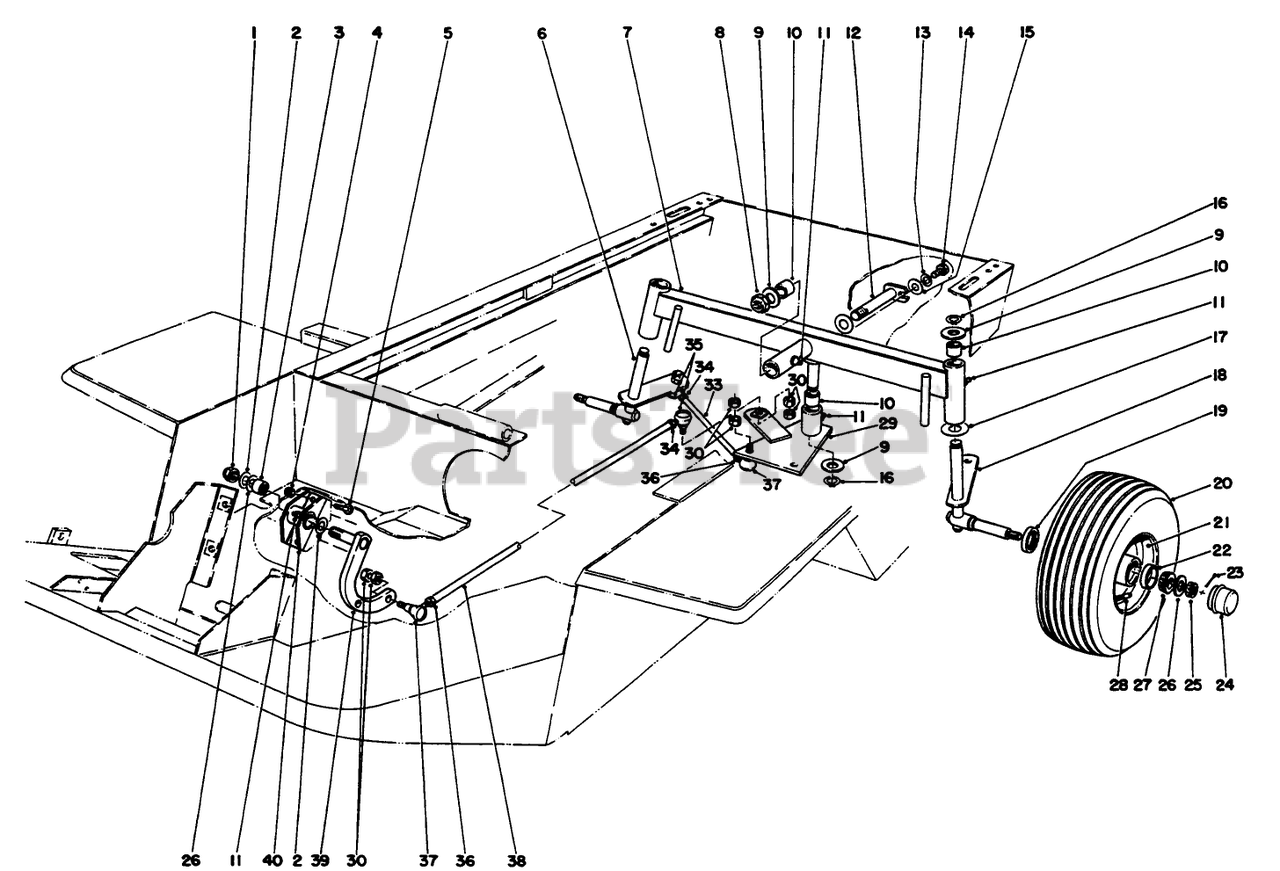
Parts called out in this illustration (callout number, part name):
1	NUT-LOCK, NI
2	THRUST WASHER
3	BEARING-NEEDLE
4	NUT-LOCK, NI
5	SCREW-HH
6	Spindle R.H.
7	Axle-Rear (Incl. Ref. #10 & 11)
8	NUT-LOCK, NI
9	WASHER-THRUST
10	BUSHING
11	FITTING-GREASE
12	Pin-RearAxle
14	SCREW-HHF
16	RING-RETAINING
17	WASHER-THRUST
18	Spindle L.H.
20	TIRE 4 PLY
21	Rim (Incl. Ref. #22)
22	BEARING-CUP, TAPERED
23	PIN-COTTER
24	CAP-DUST
25	NUT-HEX, SLOTTED
26	WASHER-FLAT
27	BEARING-CONE, TAPERED
28	VALVE STEM AND CAP ASM
29	Steering Plate Assembly (Incl. Ref. #10 & 11)
30	NUT-HJ
33	STRG TIE ROD R
34	NUT-HJ (LH THREAD)
35	LH BALL JOINT ASM
36	NUT-JAM
37	RH BALL JOINT ASM
38	REAR STRG TUBE PP
39	PIVOT ARM WA
40	Pivot Mount Assembly (Incl. Ref. #3 & 11)
